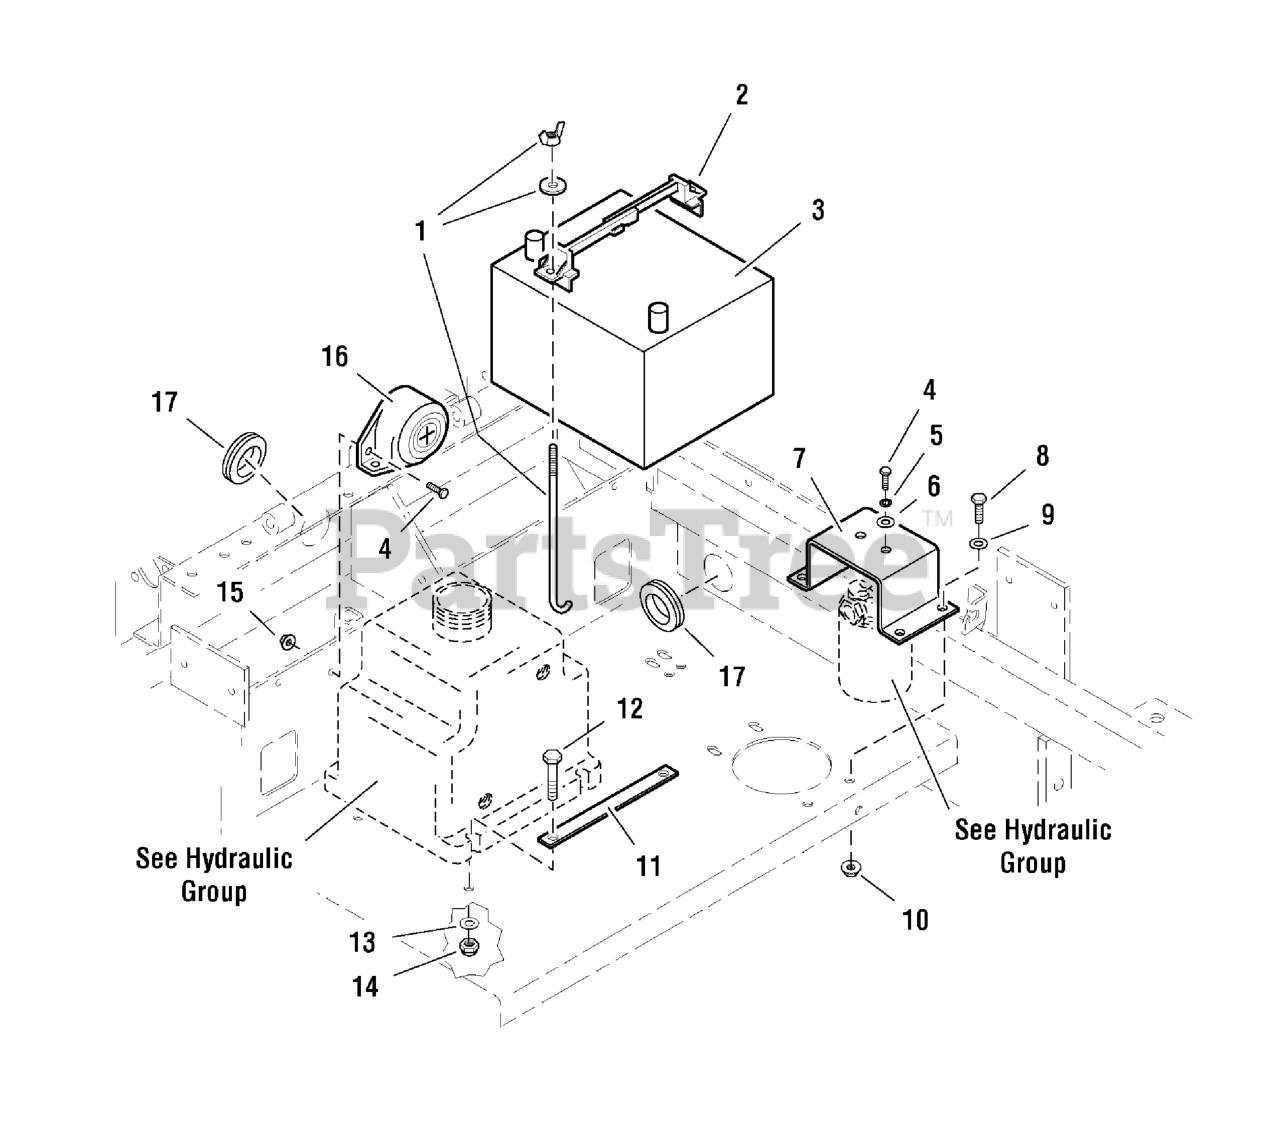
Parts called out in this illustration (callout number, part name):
1	BATTERY HOLDDOWN BOLT
2	BATTERY HOLDDOWN
3	BATTERY, 12V (BCI58, 500 CCA)
4	BOLT, 1/4-20 x 3/4
5	WASHER, 1/4 LOCK
6	WASHER, 1/4 SAE
7	OIL FILTER MOUNT
8	BOLT, 5/16-18 X 3/4 GD5
9	WASHER, 5/16" SAE
10	NUT, 5/16-18 HEX SERRATED FLANGE (SMALL)
11	HOLD DOWN PLATE
12	BOLT, 3/8-16 X 2-1/4" GD5 CZ
13	WASHER, 3/8 SAE
14	NUT, 3/8-16 HEX NYLON LOCK
15	NUT, 1/4-20 HEX SERR. FLANGE
17	GROMMET, 1-1/4"
